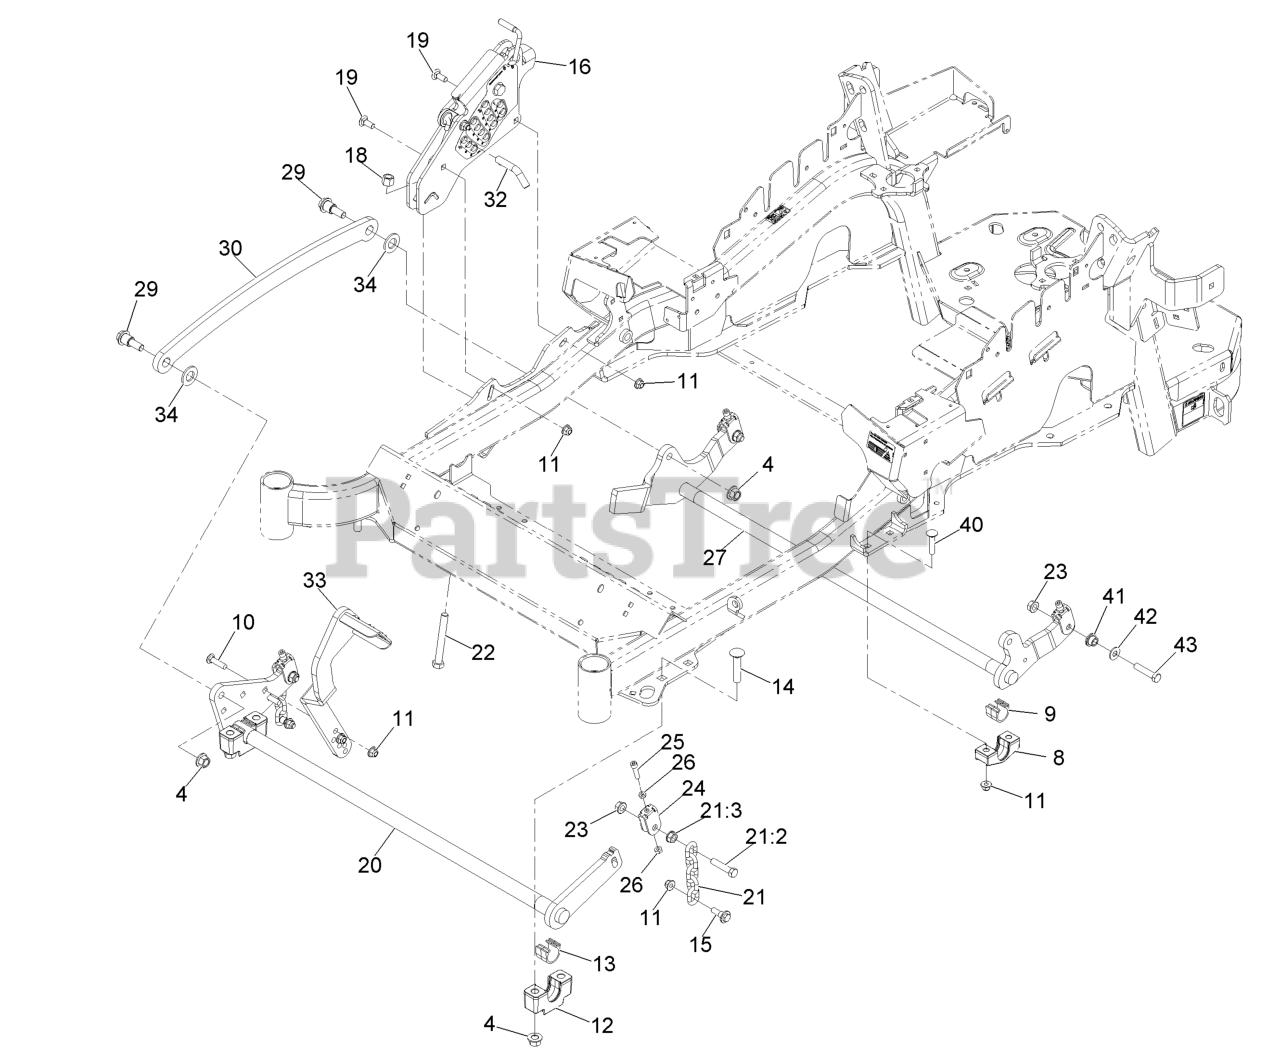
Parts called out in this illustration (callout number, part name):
4	Nut-Lock 1/2-13
9	BEARING-CROSS SHAFT, REAR
10	SCREW-CARR
11	NUT-HF, NI
12	SUPPORT-CROSS SHAFT, BEARING
13	BEARING-CROSS SHAFT, FRON
14	Bolt-Carriage 1/2-13 X 2 1/2 Spl Neck
15	SCREW-SHOULDER, HHF
16	HEIGHT-OF-CUT ASM
18	NUT-LOCK, NI
19	BOLT-CARR
21	DECK LIFT CHAIN ASM
21:2	SCREW-HH
22	BOLT-TAP
24	YOKE-ADJUST, DECK
25	SCREW-HSH
26	NUT-JAM
27	LIFT-DECK, REAR
29	SCREW-SHOULDER, HHF 1/2-13 X 1.12
30	LINK-LIFT, DECK
32	PIN-HOC
33	FOOT LEVER
34	WASHER-FLAT
40	SCREW-CARR
41	BUSHING-FLANGED
42	WASHER-FLAT
43	SCREW-HH
